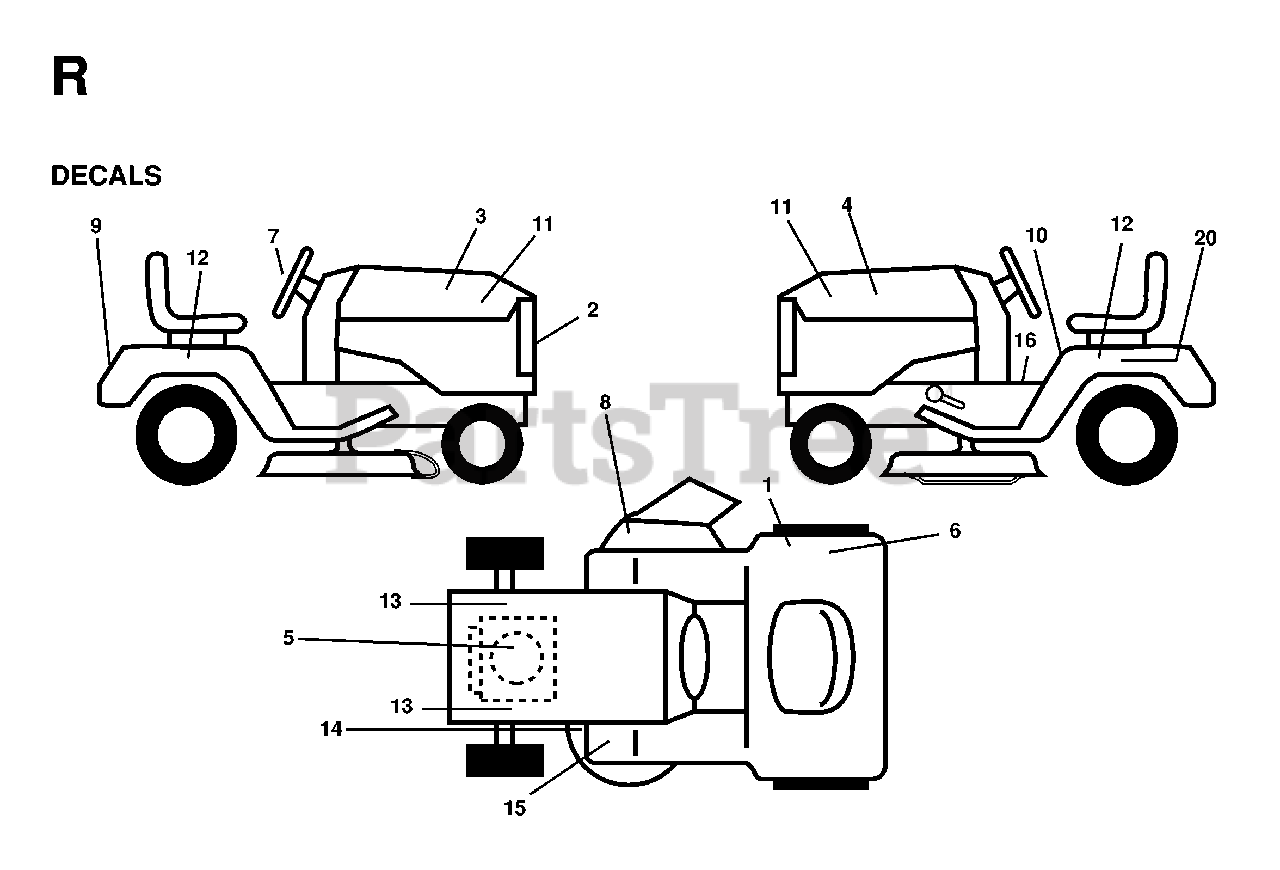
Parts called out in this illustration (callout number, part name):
1	DECAL CERTIFICATION
5	DECAL HP ENGINE
6	DECAL EUROPE STANDARD CE
8	DECAL MOWER CUT/FINGER
10	DECAL READ OWNER'S MAN SYMS
14	DECAL V BELT SCHEMATIC
16	DECAL PARK BRAKE
20	DECAL BTRY SYMBOLS
